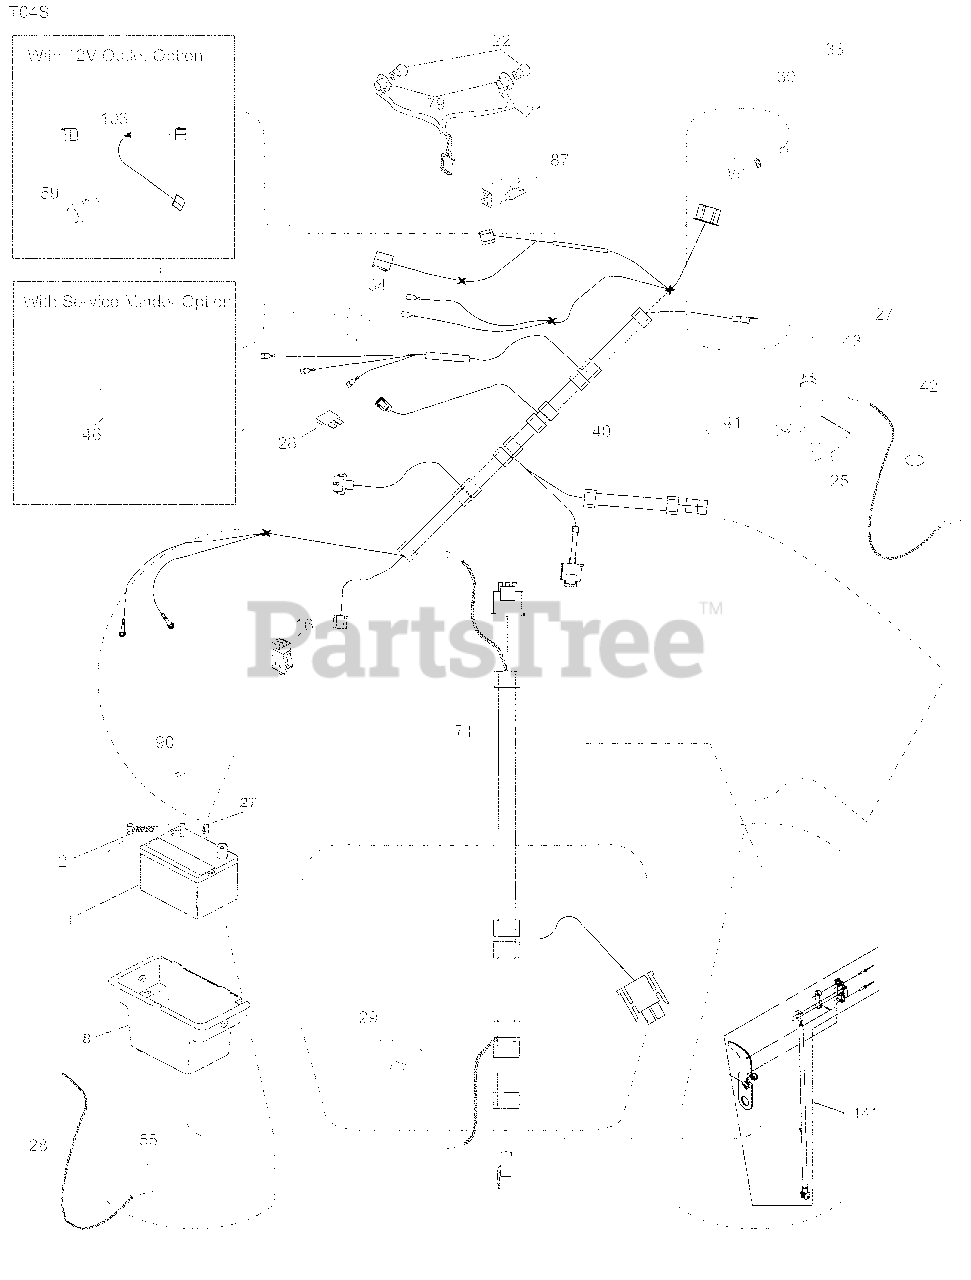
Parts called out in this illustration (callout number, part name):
1	Battery
2	Bolt Hex Head 1/4-20 x 3/4
8	Box Battery
16	Switch Interlock Push-In
21	Harness Socket Light w/4152J
22	Bulb Light
25	Cable Starter
27	Nut Keps Hex 1/4-20 unc
28	Cable, Ground
29	Switch, Seat
30	Switch, Ign
33	Key/Chain
34	Switch Light/Reset
40	Harness Ign. Dash
41	Screw Thd Cut 1/4-20 x 1/2
42	Cover, Terminal
43	Solenoid
46	Gauge Serviceminder Hrmtr
55	Screw Thdrol 5/16-18 x 3/4 TYTT
71	Harness Ign.
79	Socket Asm. Bulb
87	Switch Interlock
90	Cover Terminal
141	Kit GT ROS (71677)
